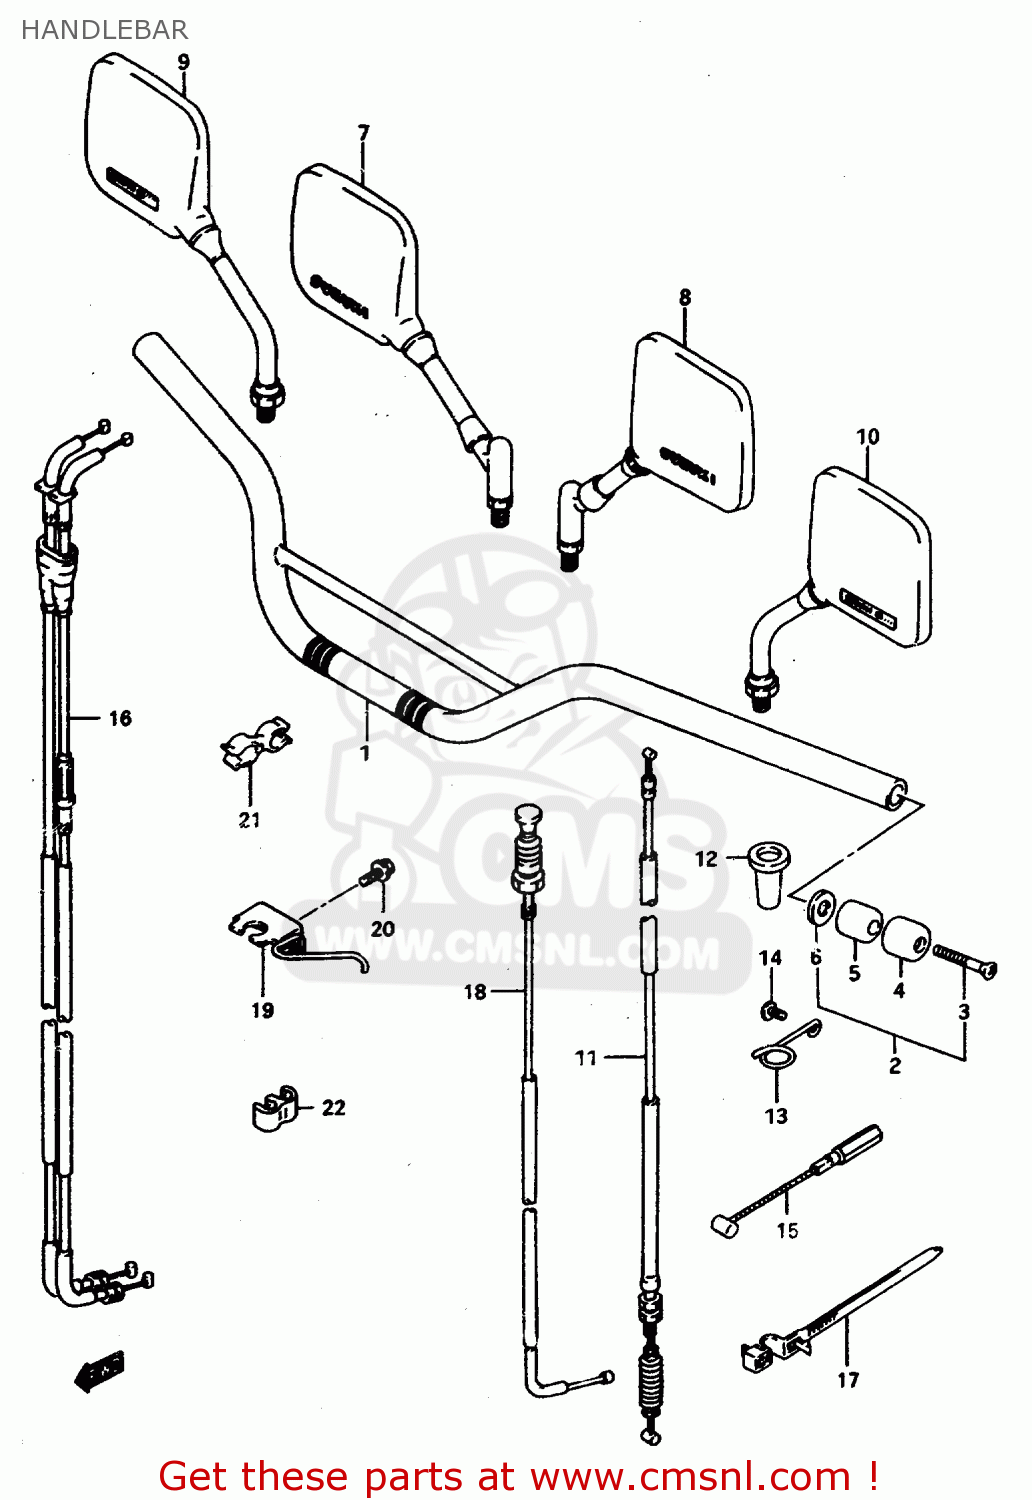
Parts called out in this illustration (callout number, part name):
1	HANDLEBAR
2	BALANCER SET,HANDLEBAR
3	SCREW
4	CAP,BALANCER
5	BALANCER,HANDLE
6	SPACER,BALANCER
7	MIRROR ASSY
8	MIRROR ASSY, L
9	MIRROR ASSY, REAR VIEW RH
10	MIRROR ASSY,RE
11	CABLE ASSY,CLUTCH
12	BOOT,CLUTCH CABLE
13	GUIDE,CLUTCH CABLE
14	SCREW 6X12
15	CABLE ASSY,DECOMP
16	CABLE ASSY,THROTTLE
17	CLAMP, CABLE
18	CABLE ASSY,STARTER
19	BRACKET,STARTER CABLE
20	BOLT
21	CLAMP
22	CLIP
